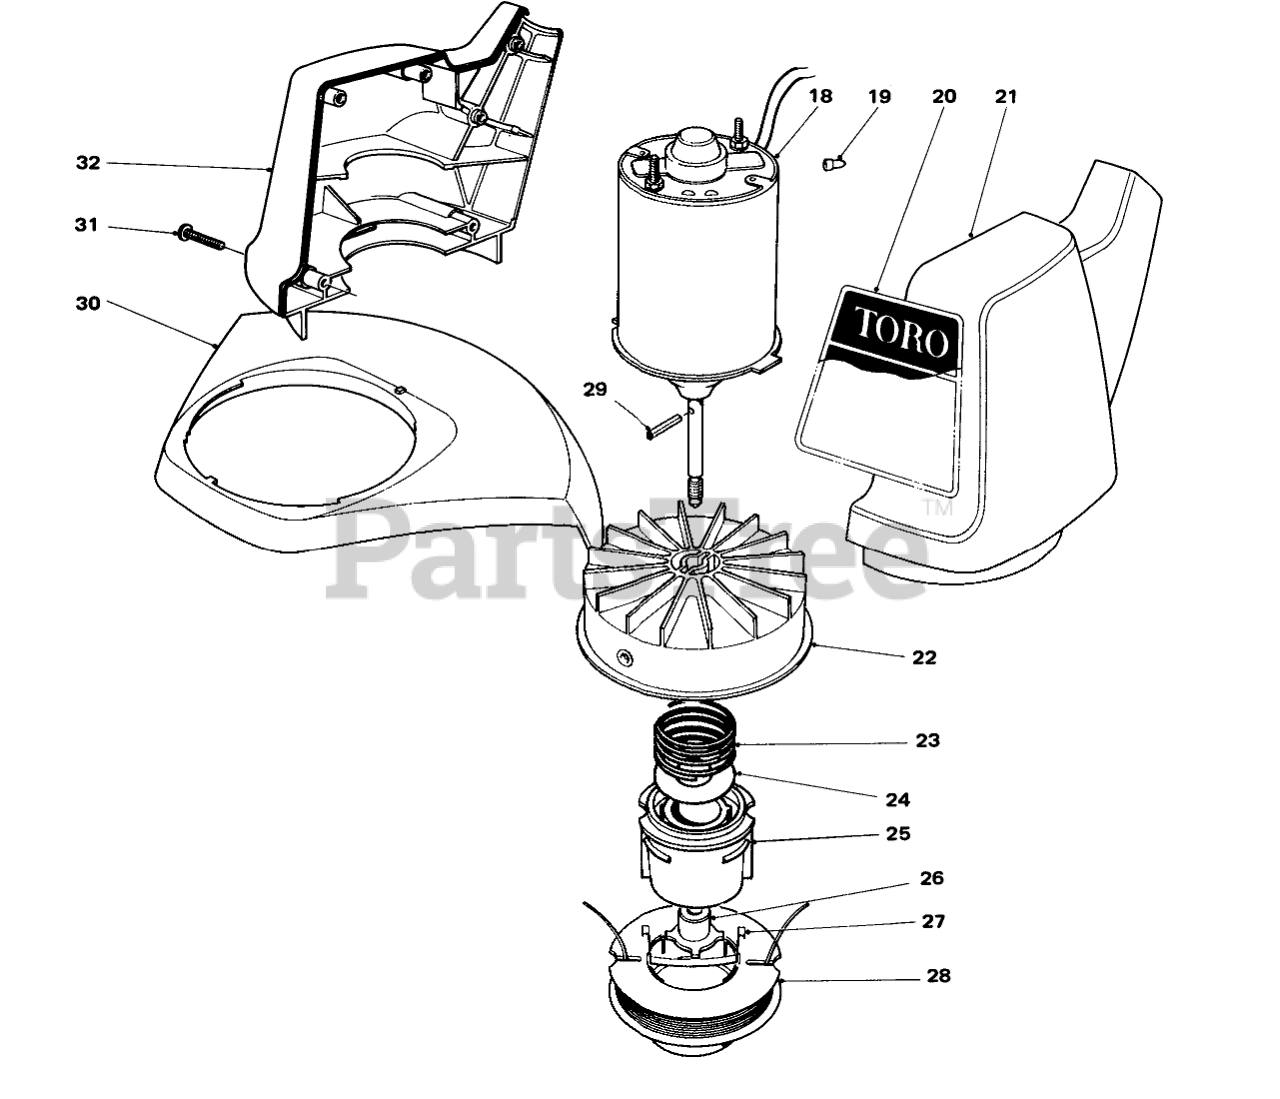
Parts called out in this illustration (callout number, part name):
18	MOTOR
19	Wire Connector
20	Decal 1200
21	Housing-L.H.
22	Drum W/Eyelets
23	SPRING COMPRESSION
24	WASHER-FLAT
25	SPOOL CORE
26	Driver
27	SADDLE-SPOOL CAP
28	Prewound Spool
29	COIL PIN
30	Shield with Cut Off Blade
31	SCREW-PPH
32	Housing-R.H.
